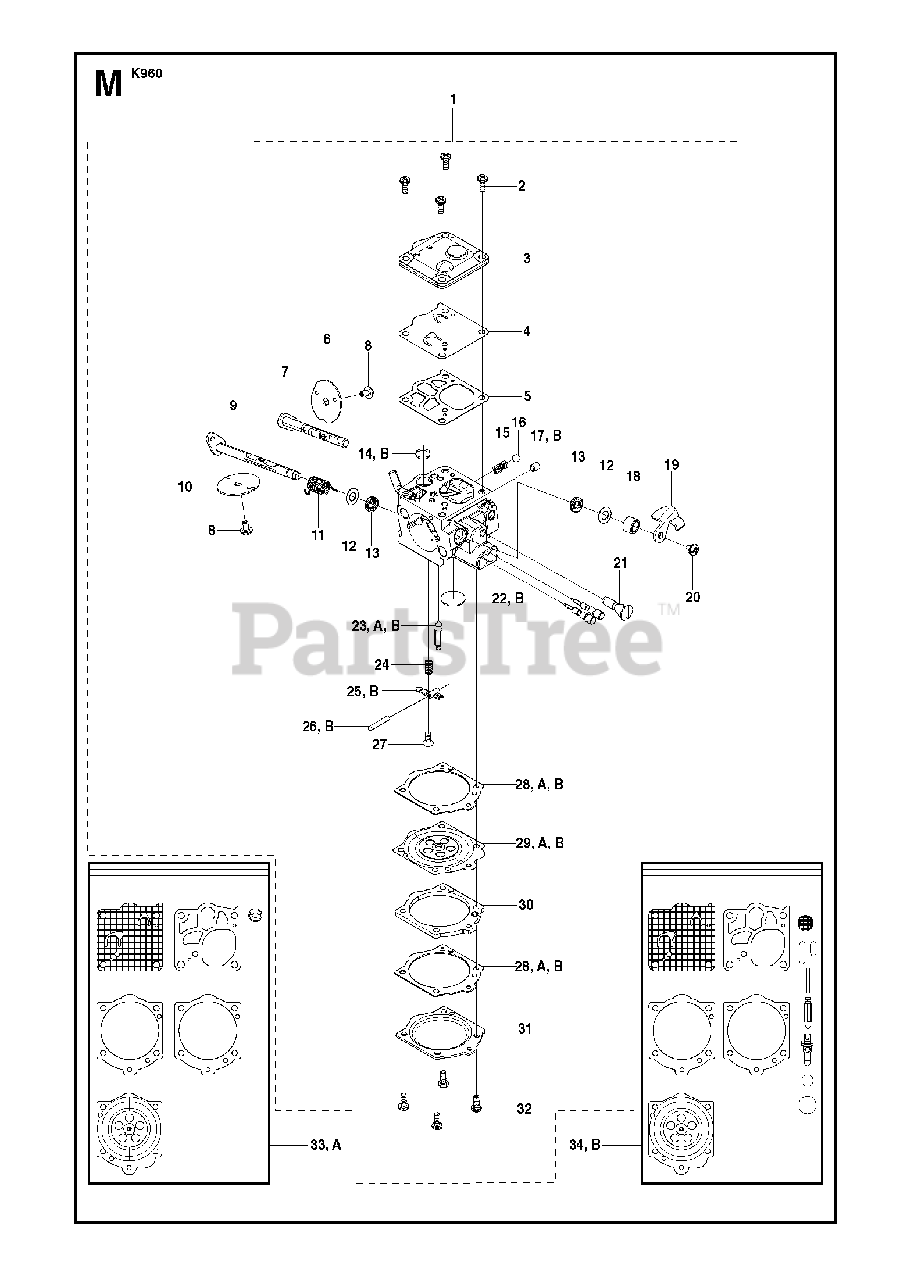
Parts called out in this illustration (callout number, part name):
1	CARBURETTORIncl. 2-23
4	DIAPHRAGM PUMPA, B
23	VALVE -INLET NEEDLEA, B
26	PIN-METERING LEVERB
29	DIAPHRAGM ASSYA, B
33	GASKET KITKit A. D10-RWJ
34	REPAIR KITKit B. K10-RWJ
